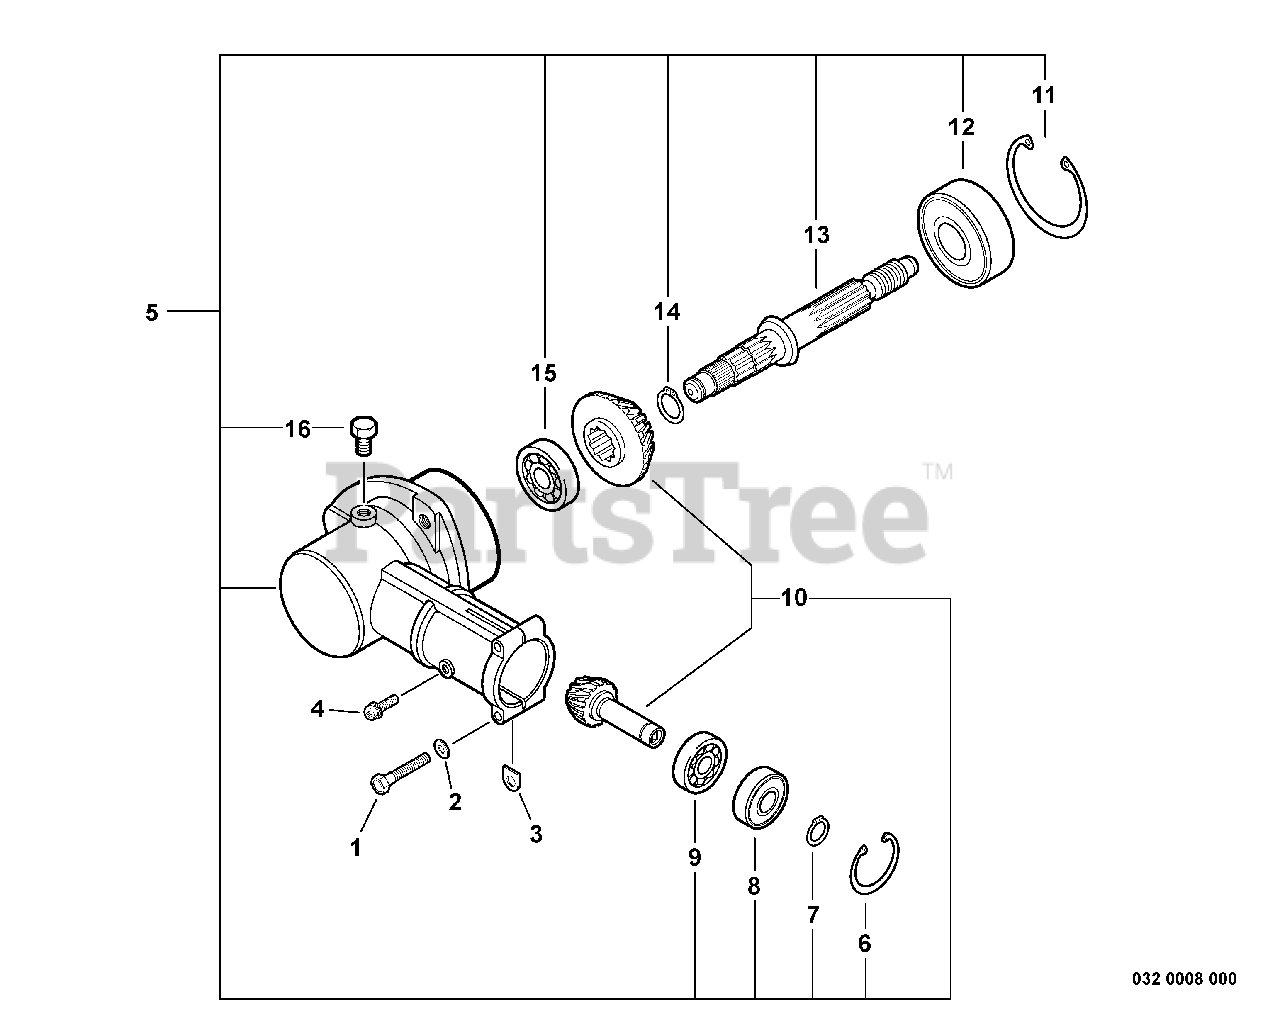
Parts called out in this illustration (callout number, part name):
1	BOLT - 5X30
2	WASHER - 5
4	SCREW - 5X12
5	GEAR CASE ASSY
6	RING, RETAINING - 22
7	RING, RETAINING - 10
8	BEARING, BALL - 6900Z
9	BEARING, BALL - 6900
10	GEAR SET
11	RING, RETAINING - 42
12	BEARING, BALL - 609
13	GEAR - SHAFT
14	BEARING, BALL - 629
15	RING, RETAINING - 12
16	BOLT - 8X8
